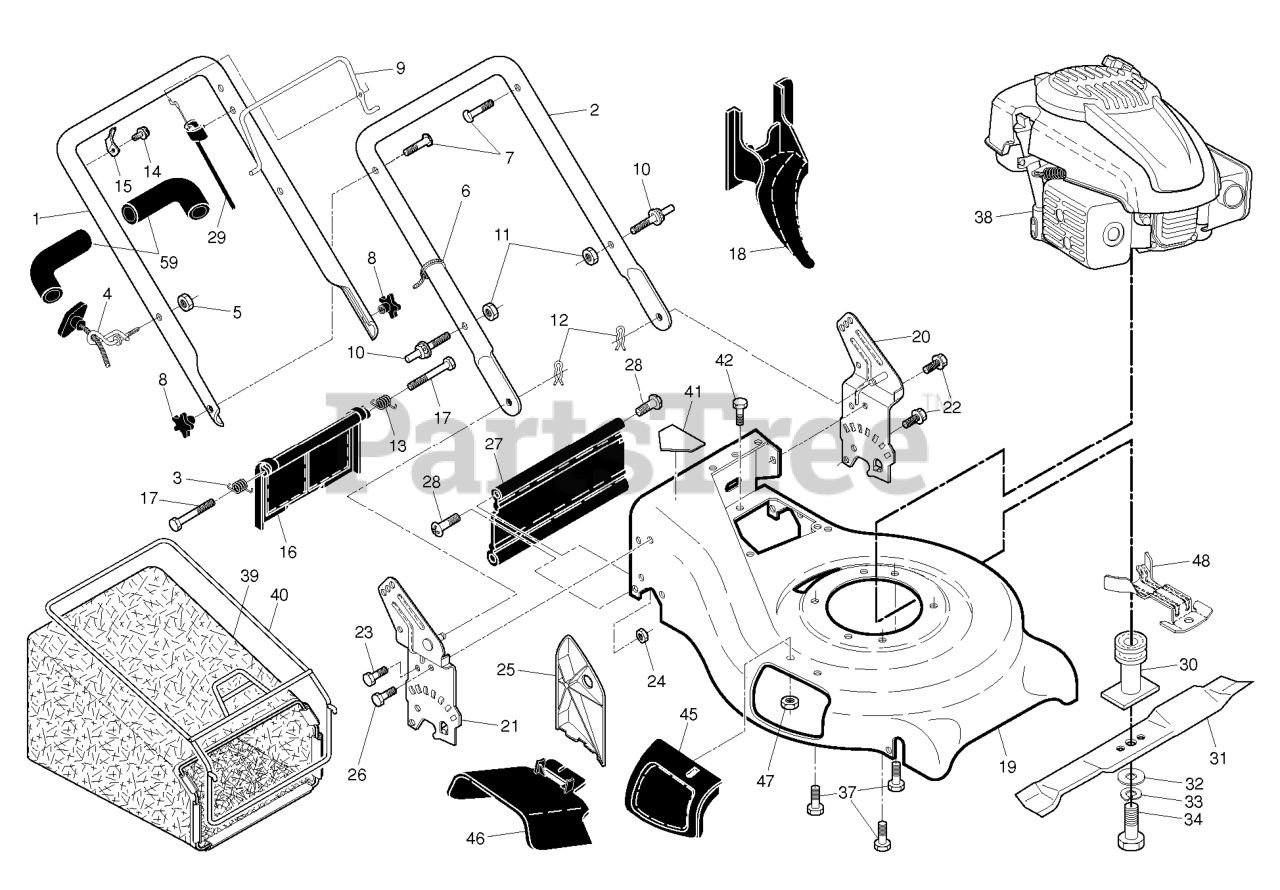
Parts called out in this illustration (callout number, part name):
1	HANDLE.ASM.UP.BS.AW2.GRIP.498
2	HANDLE.LOWER.21.GREY
3	SPRING.RH.REAR.DOOR.21.RWGD
4	RB GUIDE.ROPE.STD.BLK.ZIN WSL
5	NUT
6	TIE GUIDE
7	BOLT, HANDLE 5/16-18X1.75
8	KNOB.HANDLE.PLASTIC.STAR.BLACK
9	BAIL.CONTROL.MZR.BS.ORANGE
11	NUT.LOCK.5/16-18
12	HAIRPIN COTTER
13	SPRING.LH.REAR.DOOR.21.RWGD
15	BRACKET.UPSTOP.RT
16	REAR DOOR ASSEMBLY
18	PLUG.MULCHER.RGD.21.
19	HOUSING.21.RWD.ORANGE.WALK.
20	BRACKET.HNDL.ASM.21.RWGD.LT.OR
21	BRACKET.HNDL.ASM.21.RWGD.RT.OR
22	BOLT.HEX.HD.WASHER.5/16-18X.75
23	BOLT, HEX HEAD 5/16-18
24	NUT.71038.31-18.HEX.NYLOCK
25	CLIPPING DEFLECTOR
27	SKIRT.REAR.21.RWGD.BLACK(2 2M)
28	HINGE SCREW
29	CABLE.MZR.50.SNAP-IN
30	ADAPTER.BLADE/PULLEY.25M
31	BLADE.21.PUSH/RWGD/FWGD
32	WASHER,HARDEN
33	LOCKWASHER
34	SCREW, HEX HD 3/8-24 X 1-3/8
37	BOLT 3/8-16X1-1/8
39	RP.GBAG.93230247T.SILV.CROWN.B
40	FRAME.GBAG.21.RWGD.SC
41	DANGER DECAL
42	SCREW 14-20 X 5/8
45	MULCHER DOOR ASM.
46	DEFLECTOR, DISCHARGE
48	BRACKET.ENG/BELTKEEPER.BZP
59	GRIP.HANDLE.FOAM.WIDE.(1 SIDE)
